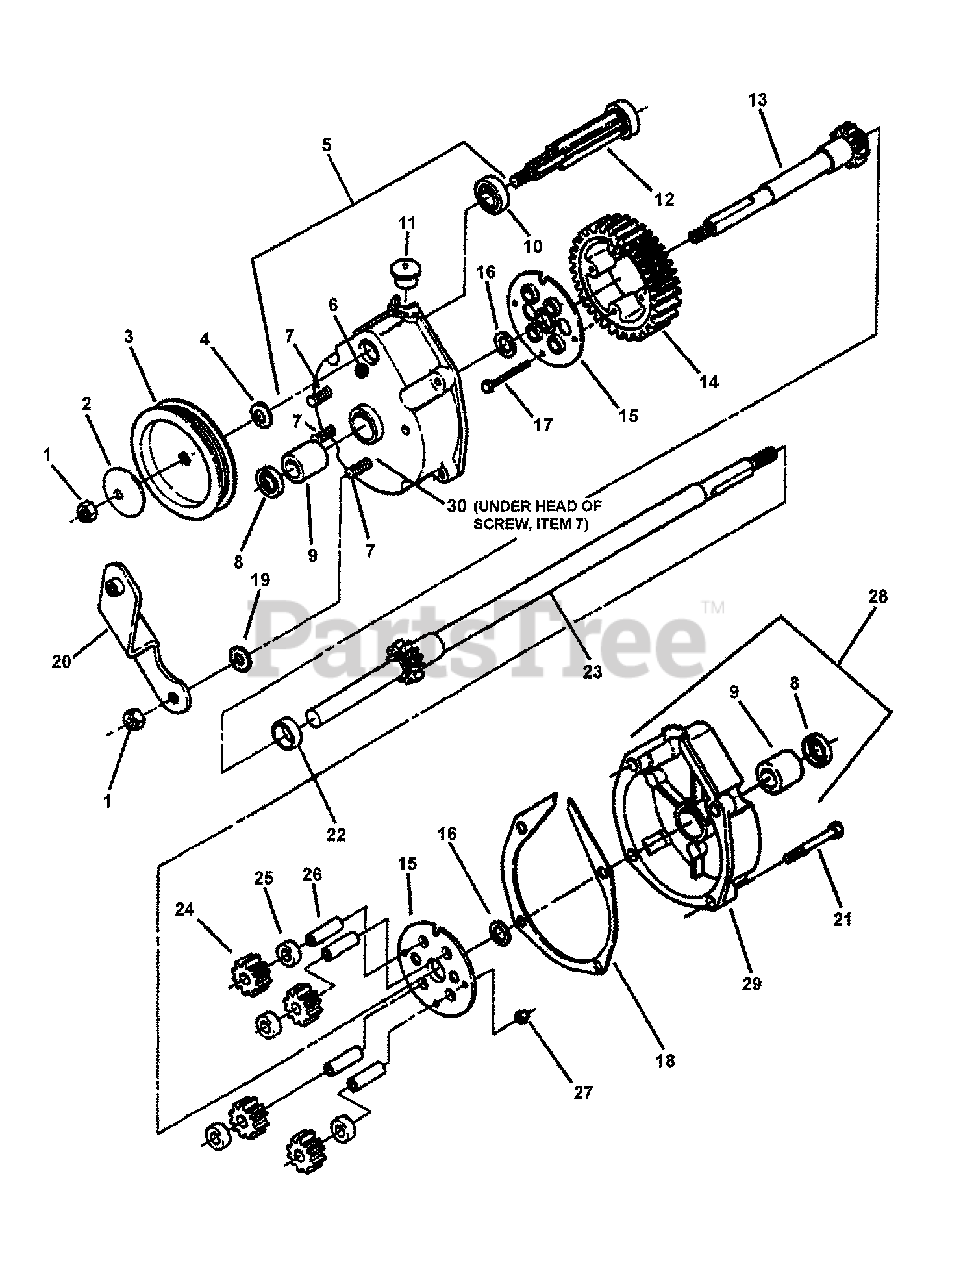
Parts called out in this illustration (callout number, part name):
1	NUT, 5/16-24 Hex Lock, GR C
2	WASHER, Cone
3	PULLEY, Poly-Vee Belt
4	WASHER, Spring
5	ASSEMBLY, Right Housing
6	HOUSING, Right Side
7	SCREW, 5/16-24 x 1-1/8" Rib Neck, GR5
8	SEAL, 5/8" Internal Dia.
9	BEARING, Tapered- (Differential Housing)
10	BEARING, Ball, .437 I.D. x 1.125 O.D. x .375 Thk.
11	PLUG, Housing
12	GEAR, Input
13	AXLE, Short
14	GEAR, Differential (46 tooth)
15	PLATE, 46T Gear
16	WASHER, Thrust, 3/4" I.D.
17	SCREW, #10-32 x 1-1/2" Hex Head Cap GR5
18	GASKET, Housing
19	WASHER, 5/16" Internal/External Tooth Lock
20	BRACKET, Differential
21	SCREW, 1/4-20 x 1-1/4" Hex Washer Self-Tap
22	SPACER, Axle Gear
23	AXLE, Long
24	GEAR, Pinion (12 tooth)
25	SPACER, Pinion Gear
26	SHAFT, Pinion
27	NUT, #10-32 Hex Nyloc
28	ASSEMBLY, Left Housing
29	HOUSING, Left
30	GASKET, 5/8" O. D.
